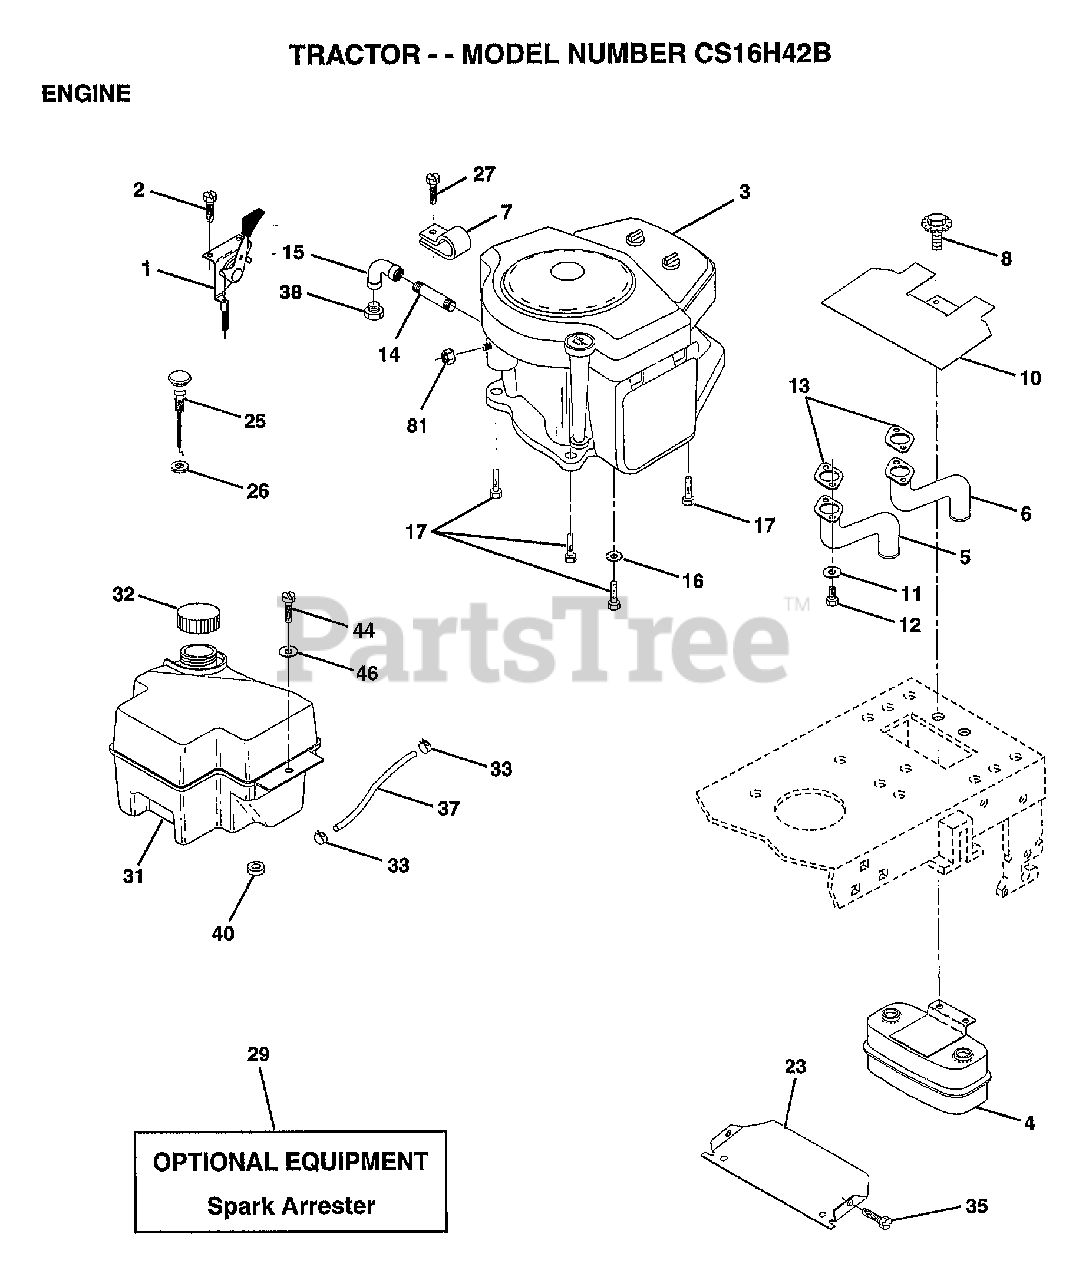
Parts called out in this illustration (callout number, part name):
1	CONTROL THRT 35.5
2	SCREW LT
3	ENGINE, BRIGGS
4	MUFFLER.TW.LOTONE
5	EXHAUST.B&S.18.LH
6	EXHAUST.B&S.18.RH
7	CLAMP.TUBE.DBL.EN
8	BOLT.5/16-18.UNC
10	SHIELD.HEAT.
11	LOCKWASHER
13	GASKET MUFFLER
14	PIPE NIPPLE LT
15	ELBOW
16	LOCKWASHER
17	SCREW LT
23	SHIELD-HEAT
25	CONTROL.CHOKE.37
26	"NUT,KEPS 3/8-24IM"
27	"SCREW-TT,10-32 FL"
32	CAP ASM FUEL
33	HOSE CLAMP
35	SCREW
37	LINE FUEL
44	SCREW HEX CRT
46	WASHER
81	NUT
